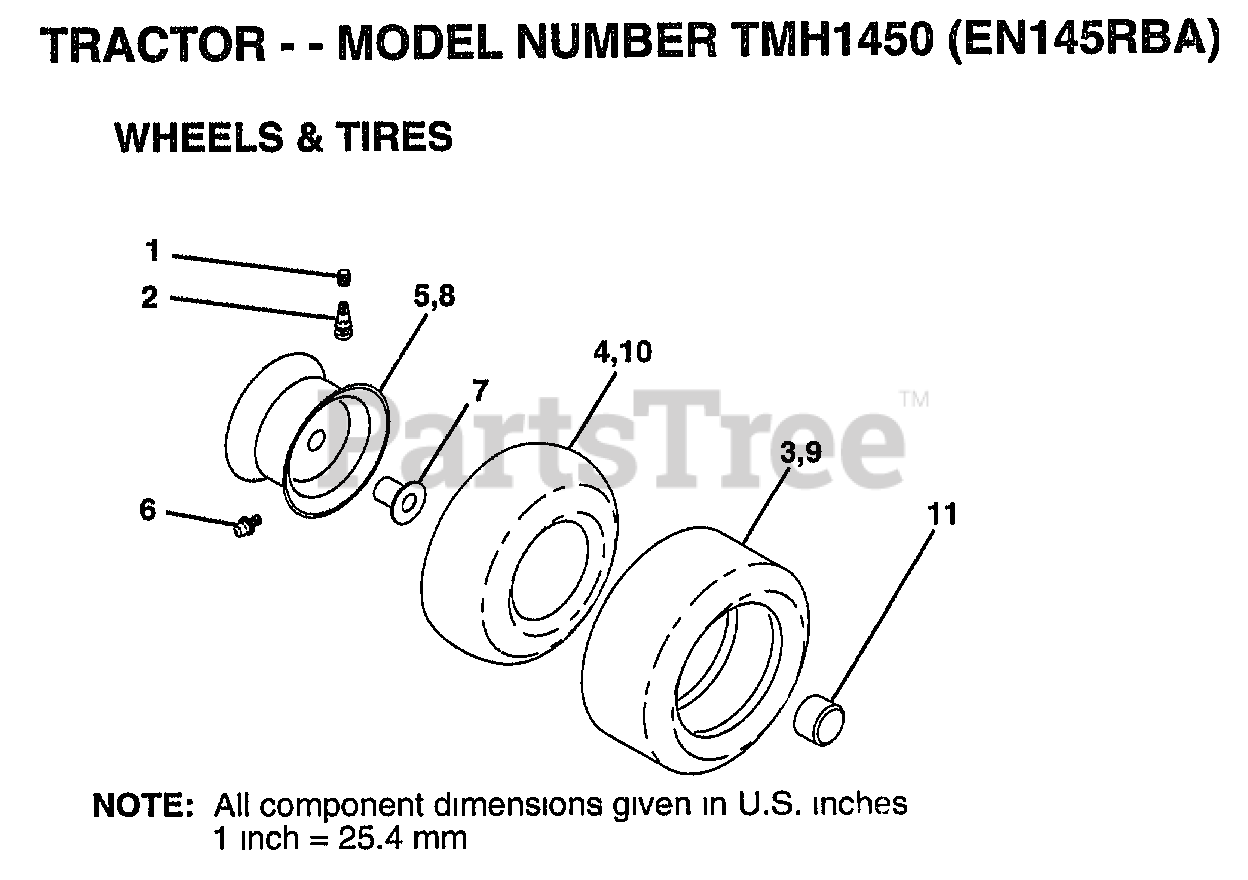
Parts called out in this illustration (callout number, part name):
1	VALVE CAP
2	VALVE STEM LT
4	TUBE.5.3/4.5/6
5	RIM.FRONT.6.YELLO
6	FITTING LT
7	"FLANGE, BEARING"
10	TUBE.18X9.5-8
11	HUB CAP
